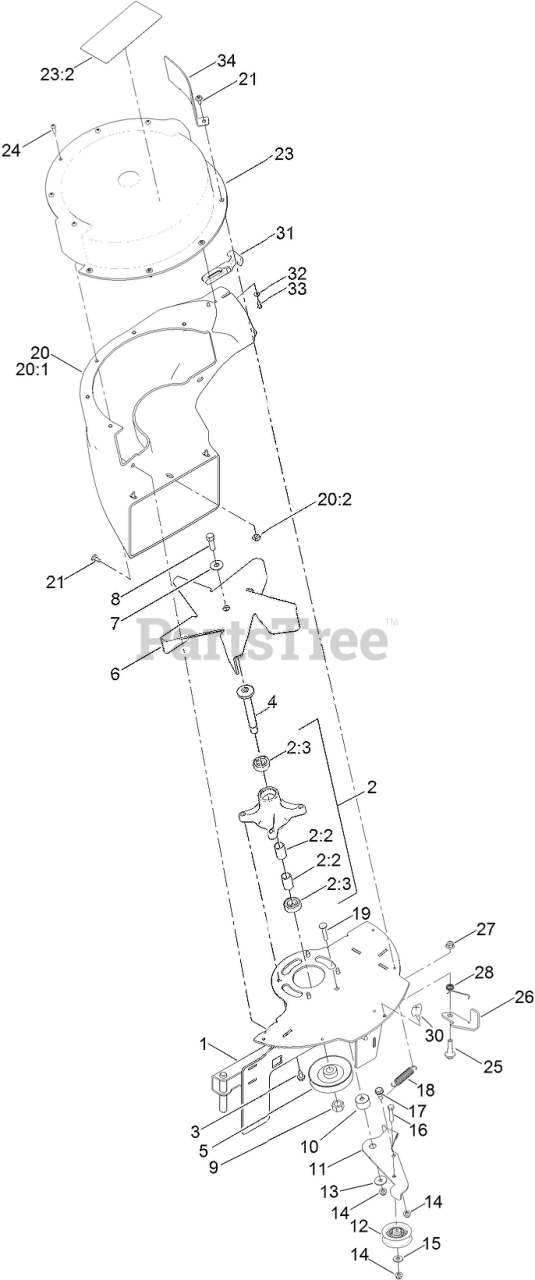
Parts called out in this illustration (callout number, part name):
1	FRAME-BLOWER
2	SPINDLE ASM
2:2	SPACER
2:3	BEARING-BALL
3	SCREW-HWHTF
4	SHAFT-SPINDLE
5	PULLEY-BLOWER
6	FAN-BLOWER
7	WASHER-BELLEVILLE
8	SCREW-HH
9	NUT-HEX
10	SPACER-ARM, IDLER
11	BLOWER-ARM, IDLER
12	PULLEY-IDLER
13	WASHER-PIVOT
14	NUT-HF, NI
15	WASHER-FLAT
16	SCREW-HH
17	BOLT-SHOULDER
18	SPRING-RETURN, PEDAL
19	SCREW-HH
20	BLOWER CHUTE ASM
20:1	CHUTE-BLOWER
20:2	INSERT-T-NUT
21	SCREW-SHOULDER
23	BLOWER COVER ASM
23:2	DECAL-DANGER
24	SCREW-PRH
25	BOLT-SHOULDER
26	LATCH-BLOWER
27	NUT-HF, NI
28	SPRING-TORSION
31	LATCH-RUBBER
32	WASHER-FLAT
33	SCREW-PPH
34	GUARD-BLOWER
